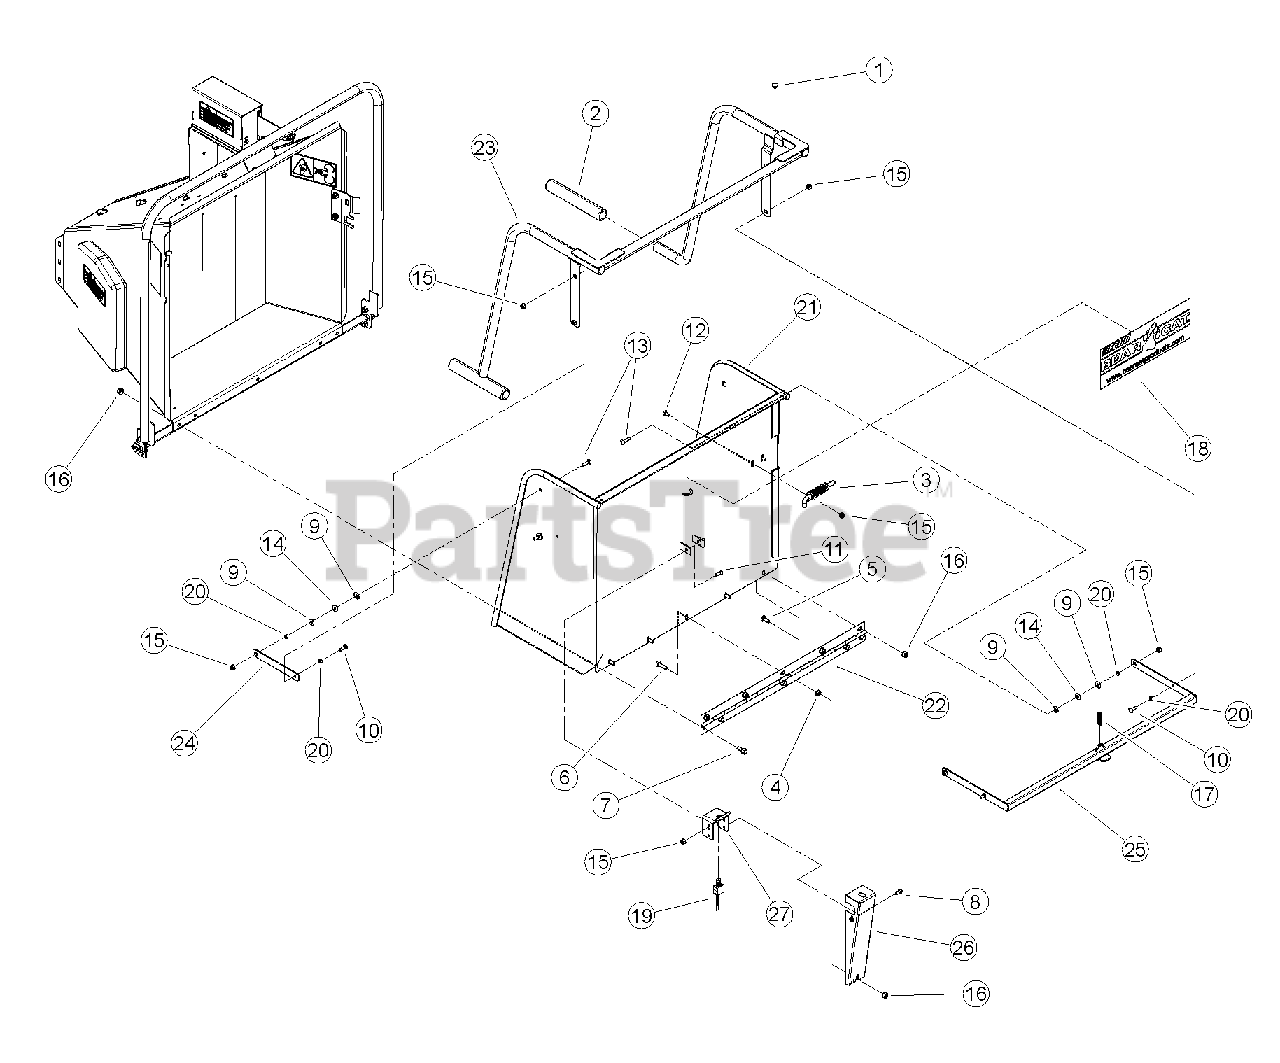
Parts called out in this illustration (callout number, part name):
1	BUMPER, RUBBER
2	GRIP, 1.219 X 10.00
3	LATCH, RH HINGE
4	NUT, 3/8" SERRATED FLANGE NC ZP
5	BOLT, 3/8 X 1-1/2" GR5 CRG NC ZP
6	BOLT, 3/8 X 1 FLANGE NC
7	SCREW, 11/32 X 7/8 HWH AB THREAD ZP
8	WASHER, 5/16" FLAT ZP
9	BOLT, 5/16 X 1" GR5 CRG ZP
10	BOLT, 5/16 X 7/8" GR5 CRG NC ZP
11	BOLT, 5/16 X 3/4 GR5 CRG NC ZP
12	BOLT, 5/16 X 1-1/4" GR5 CRG ZP
13	WASHER, 5/16" ID 7/8" OD NYLON FLAT
14	NUT, 5/16-18 NYLOCK-FLANGE
15	NUT, 3/8-16 NYLOCK FLANGE
16	SPRING, 1/2 X 2.00 LG ZP
17	DECAL, BEARCAT WEB
18	SWITCH, MOMENTARY IP67 NORMALLY ON
19	SPACER, IDLER PIVOT
20	WELDMENT, EXTENSION TRAY
21	HINGE, EXTENSION TRAY
22	WELDMENT, KNEEBAR
23	LINK, PARALLEL
24	WELDMENT, KNEEBAR PIVOT
25	SHIELD, KNEEBAR SWITCH
26	BRACKET, SWITCH
